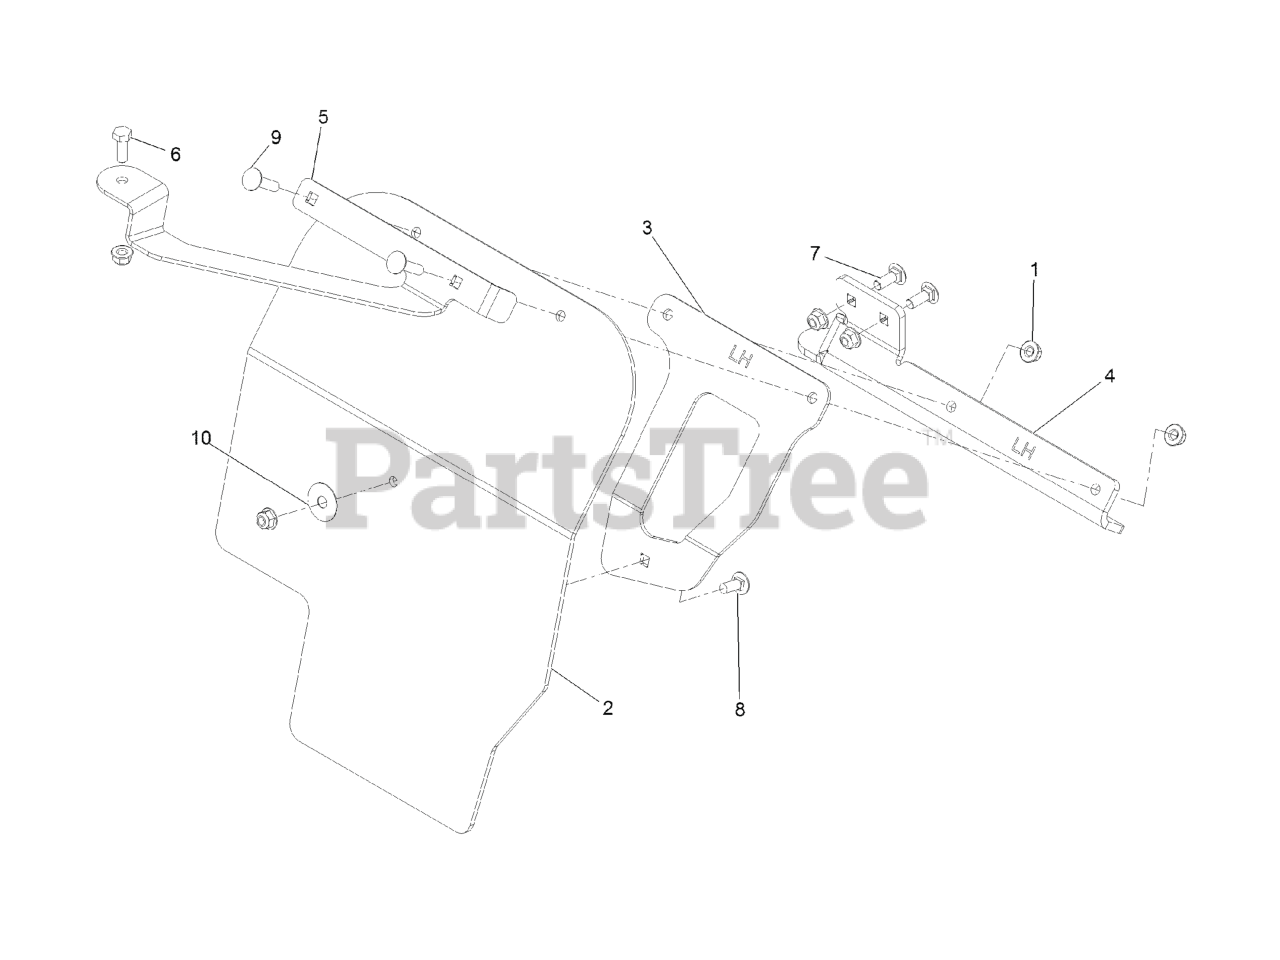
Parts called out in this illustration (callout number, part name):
1	NUT-HF, NI
2	LH MUD FLAP
3	SUPPORT, LH MUD FLAP
4	BRACKET, LH MUD FLAP
5	FORWARD SUPPORT, LH MUD FLAP
6	SCREW-HH
7	SCREW-CARR
8	SCREW-CARR
9	Bolt-Carriage 5/16-18 X 1 1/4
10	WASHER-PLAIN
